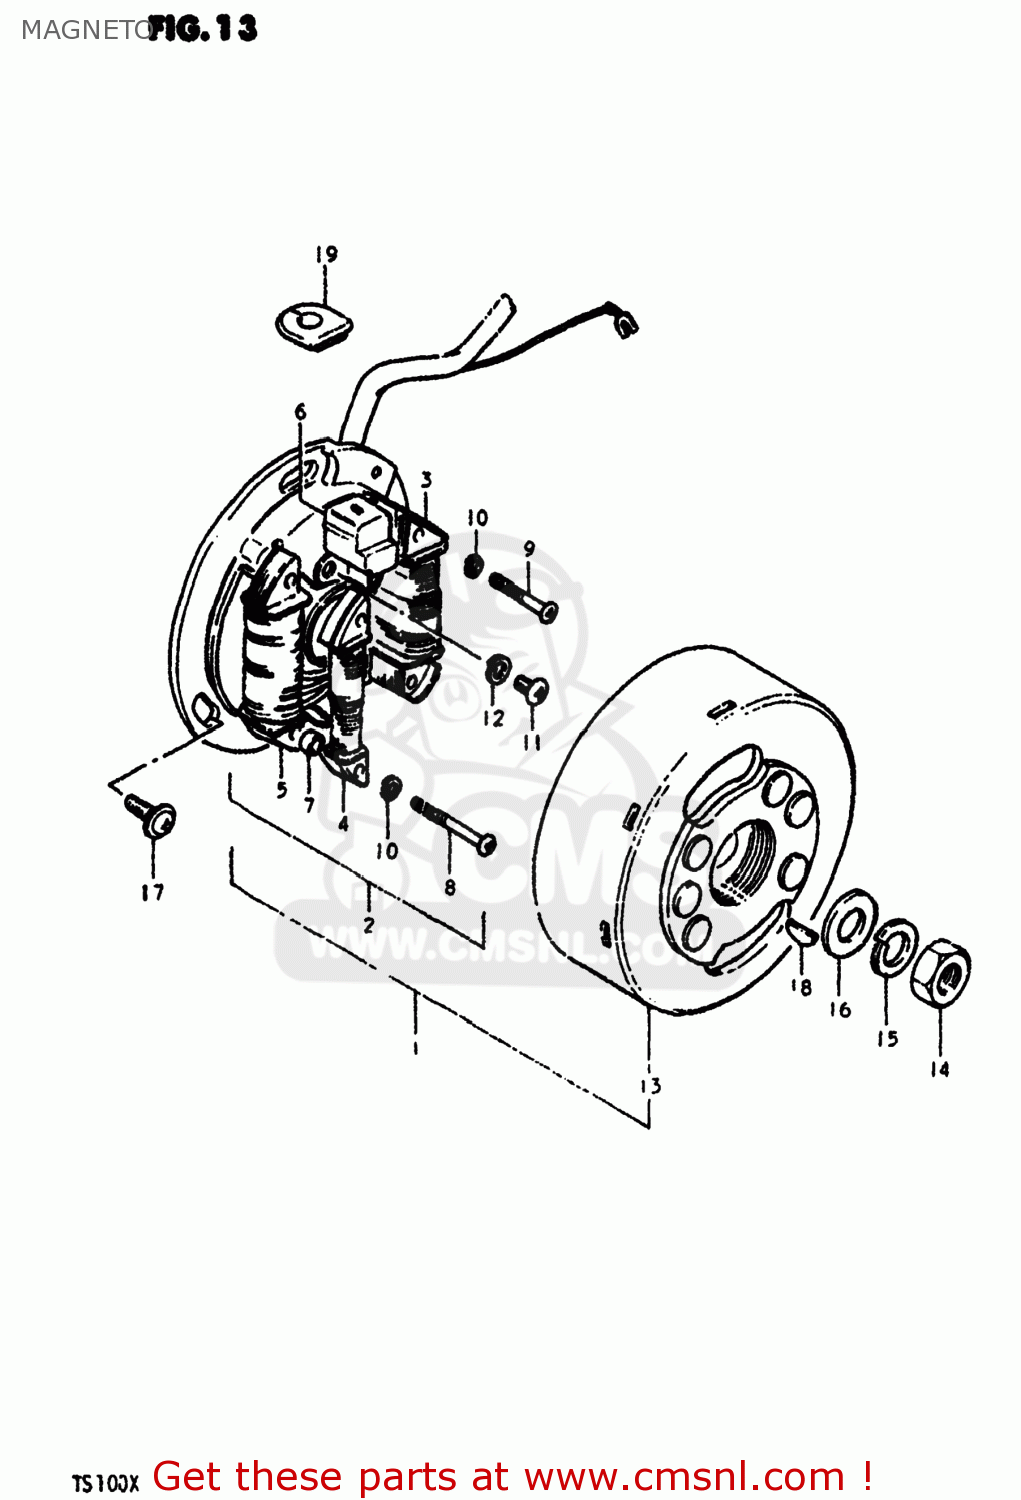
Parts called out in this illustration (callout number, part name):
1	MAGNETO ASSEMBLY
2	STATOR ASSEMBLY
3	COIL,LIGHTING
4	COIL,CHARGING
5	COIL,PRIMARY
6	COIL,PULSER
8	SCREW (4X30)
9	SCREW 4X25
10	LOCK WASHER
11	SCREW
12	LOCK WASHER
13	ROTOR,FLYWHEEL
14	NUT (10MM)
15	LOCK WASHER
16	WASHER
17	SCREW(5X14)
18	KEY
19	GROMMET
